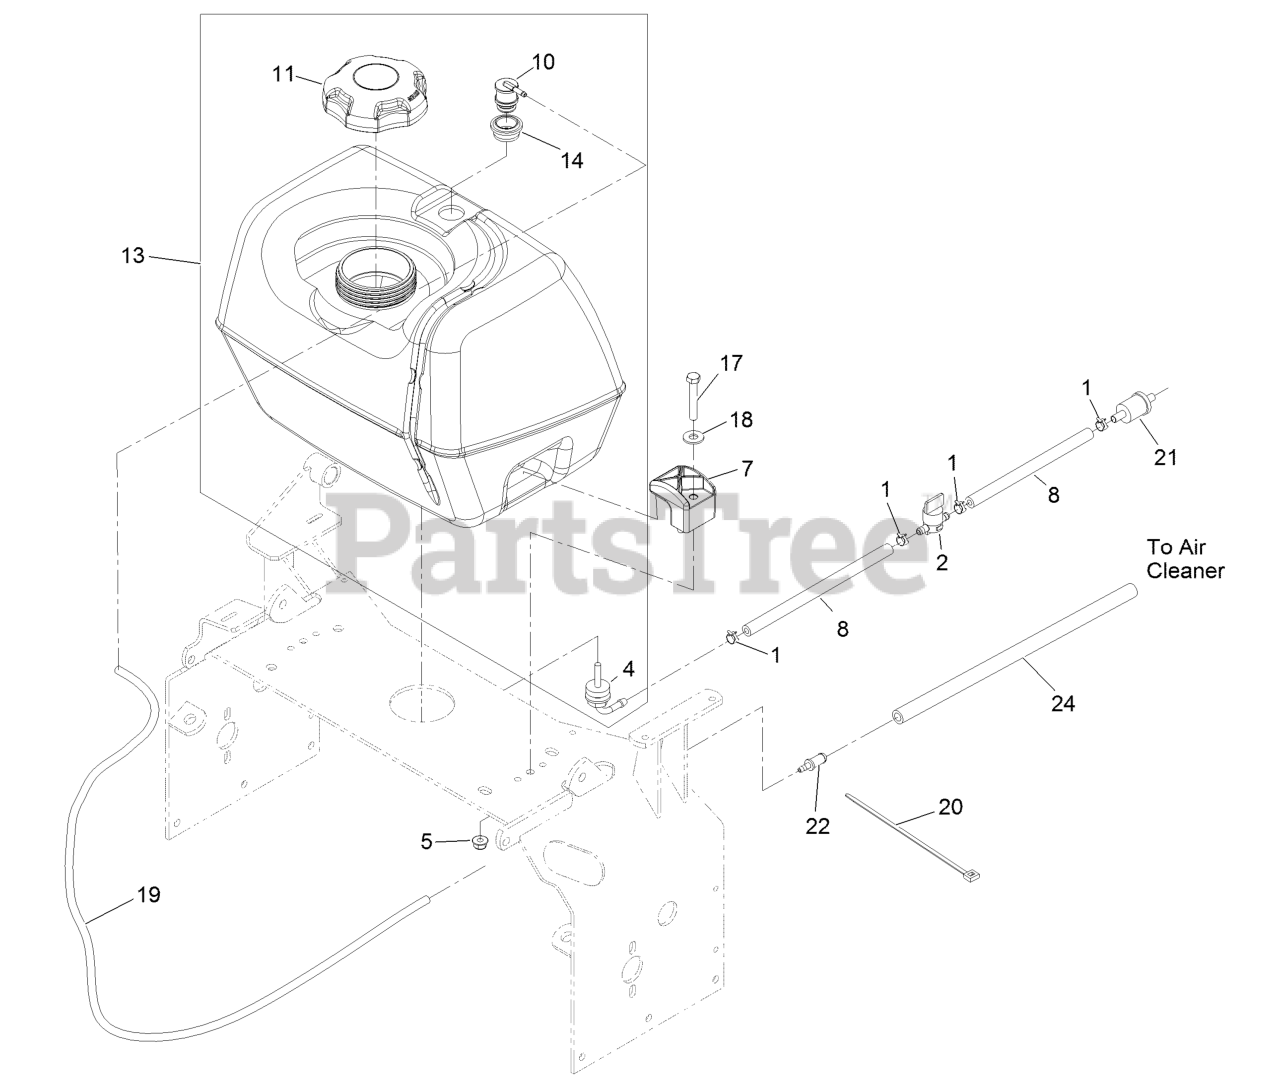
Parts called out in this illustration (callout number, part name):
1	CLAMP-HOSE
2	VALVE-FUEL
4	FITTING-FUEL, BULKHEAD
5	NUT-HF, NI
8	HOSE-FUEL
10	VALVE-VENT, FUEL
13	ASM, FUEL TANK
14	GROMMET
17	SCREW-HH
18	WASHER-FLAT
19	HOSE-EMISSIONS
20	TIE-PLASTIC
21	Pn 49019-0014 Filter W/6in Fuel Line
22	FITTING-STRAIGHT
24	HOSE-FUEL
